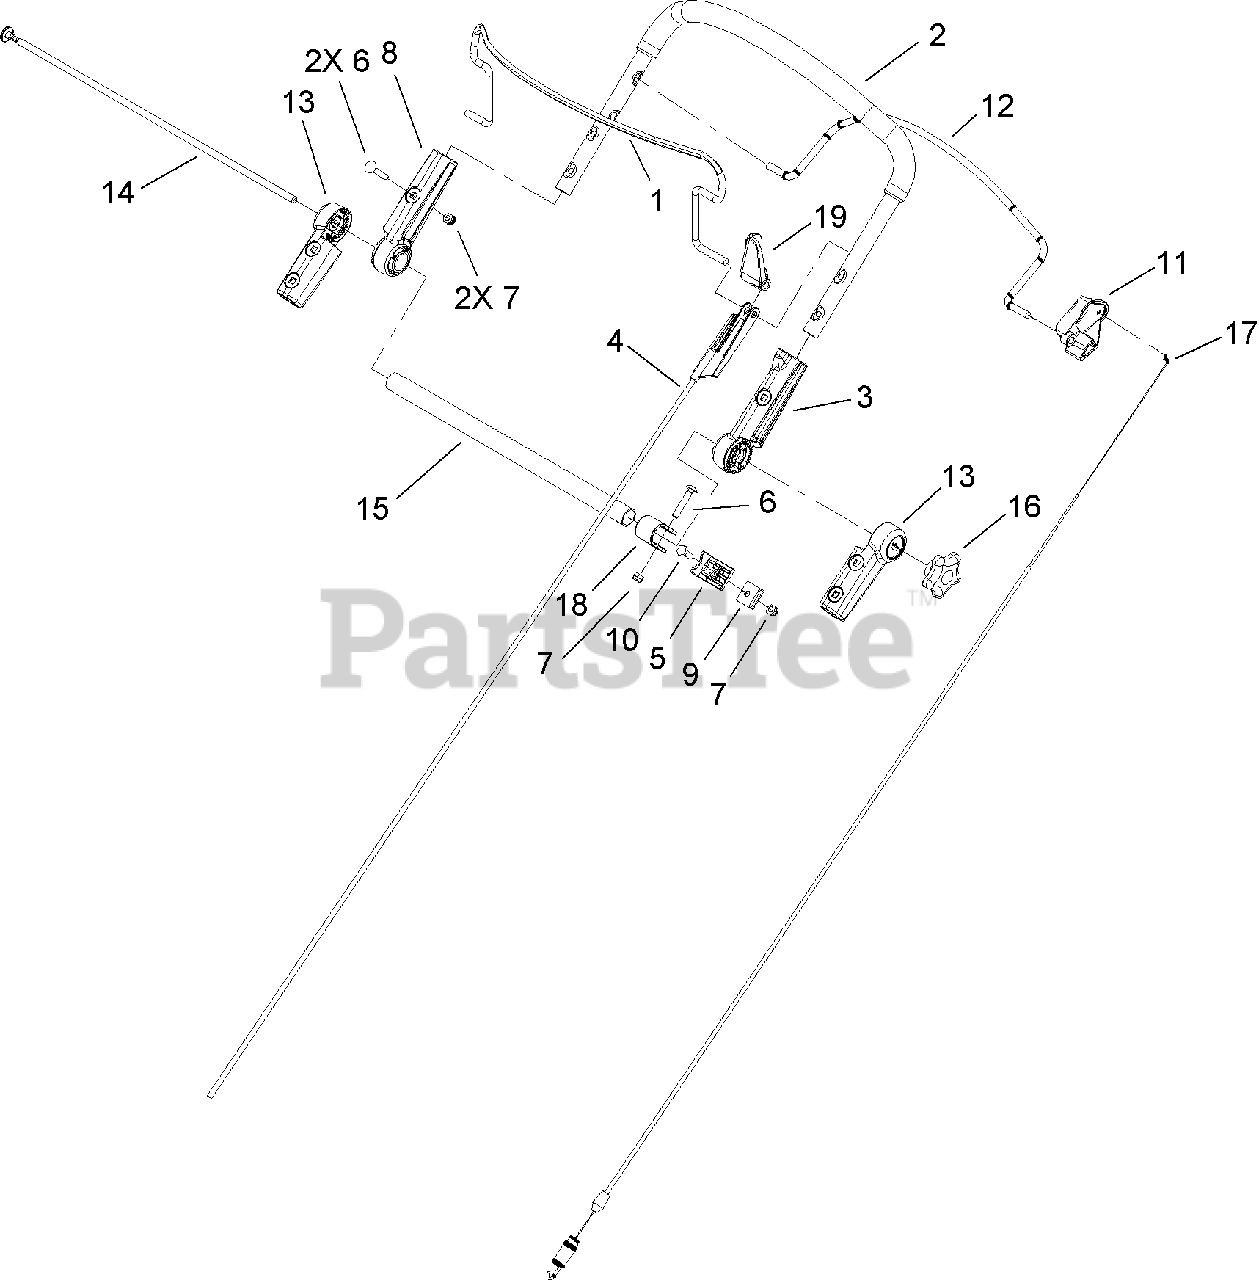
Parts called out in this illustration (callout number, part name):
2	HANDLE ASM
3	MOUNT-HANDLE, LH
4	CABLE-BRAKE
5	SUPPORT-GUIDE, CABLE
6	SCREW-CARR
7	NUT-LOCK, NI
8	MOUNT-HANDLE, RH
9	CLAMP-CABLE
10	SCREW-HH
11	STOP-BAIL
12	BAIL-TRACTION
13	MOUNT-HANDLE, LOWER
14	ROD-THREADED
17	CABLE-TRACTION
18	SUPPORT-CABLE
19	STOP-PIVOT
